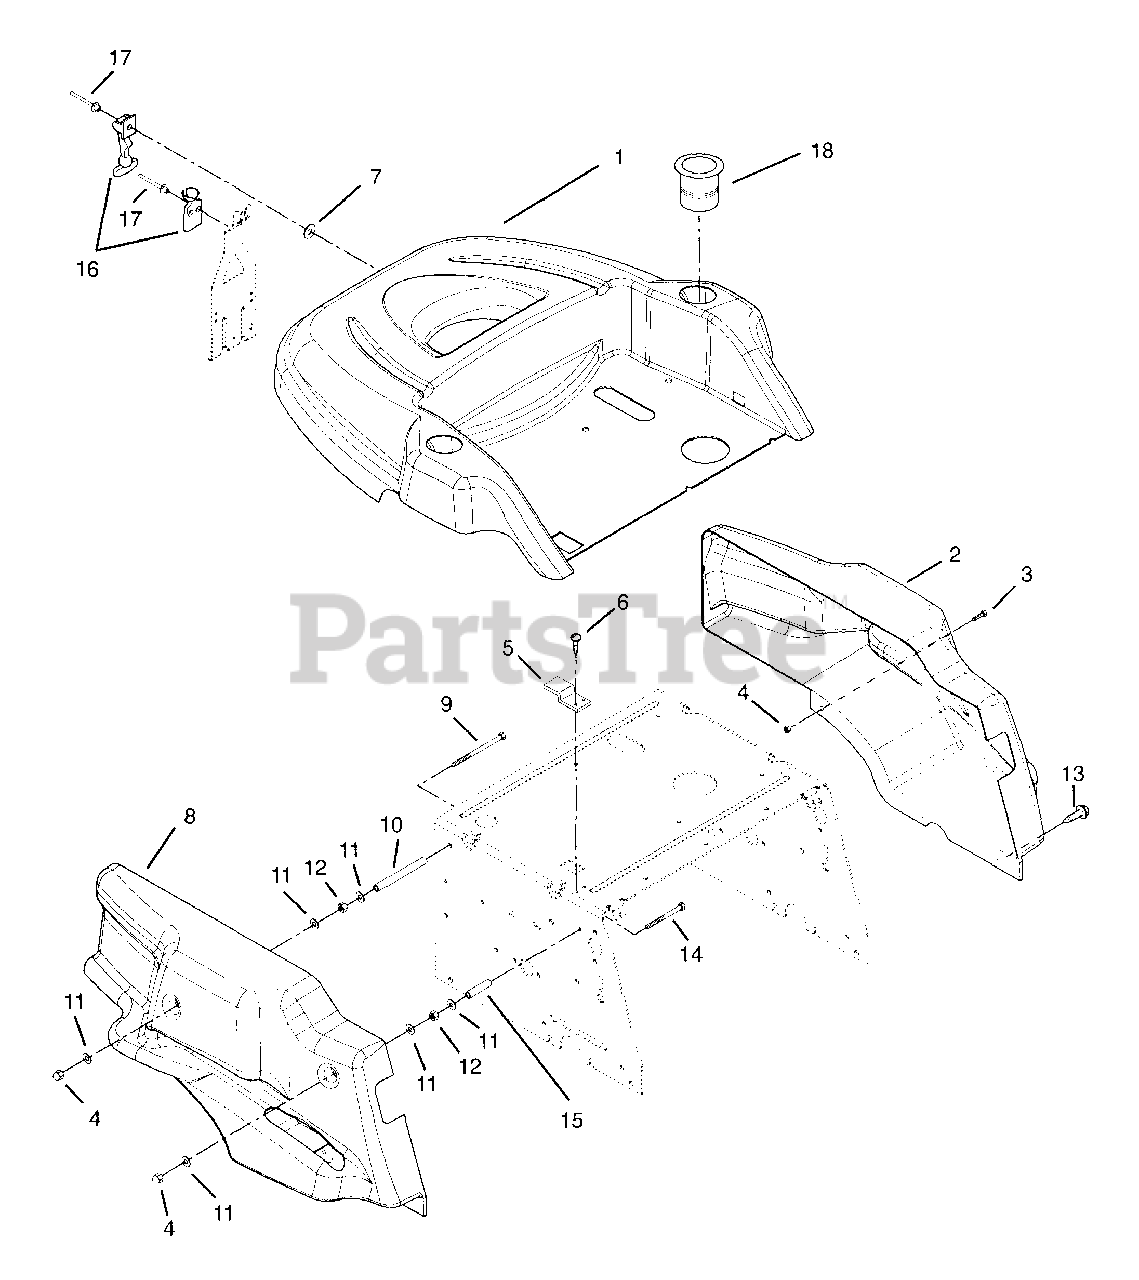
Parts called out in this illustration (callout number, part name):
1	SHROUD, TOP
2	SHROUD, SIDE LH
3	@BLT-HEX .31-18X1.00 GR5 YWZC
4	@NUT-LK-NYL .312-18 YWZC
5	CLIP YWZC
6	@SCR-TAP .25-20X.50 HWH TR YWZ
7	RVT-BURR .125X.505X.048
8	SHROUD, SIDE RH
9	@BLT-HEX .31-18X5.50 GR5 YWZC
10	SPACER, .328 X .462 X 4.42 YWZ
11	@WSHR-FL-STL.344X.688X.065YWZC
12	@NUT-HEX .31-18 YWZC
13	@SCR-TAP .31-18X.75 HWH TR YWZ
14	@BLT-HEX .31-18X3.00 GR5 YWZC
15	SPACER, .328 X .462 X 1.92 YWZ
16	LATCH,FLEXIBLE
17	ABA46 BLIND RIVET (AB4-6A)
18	CUPHOLDER
